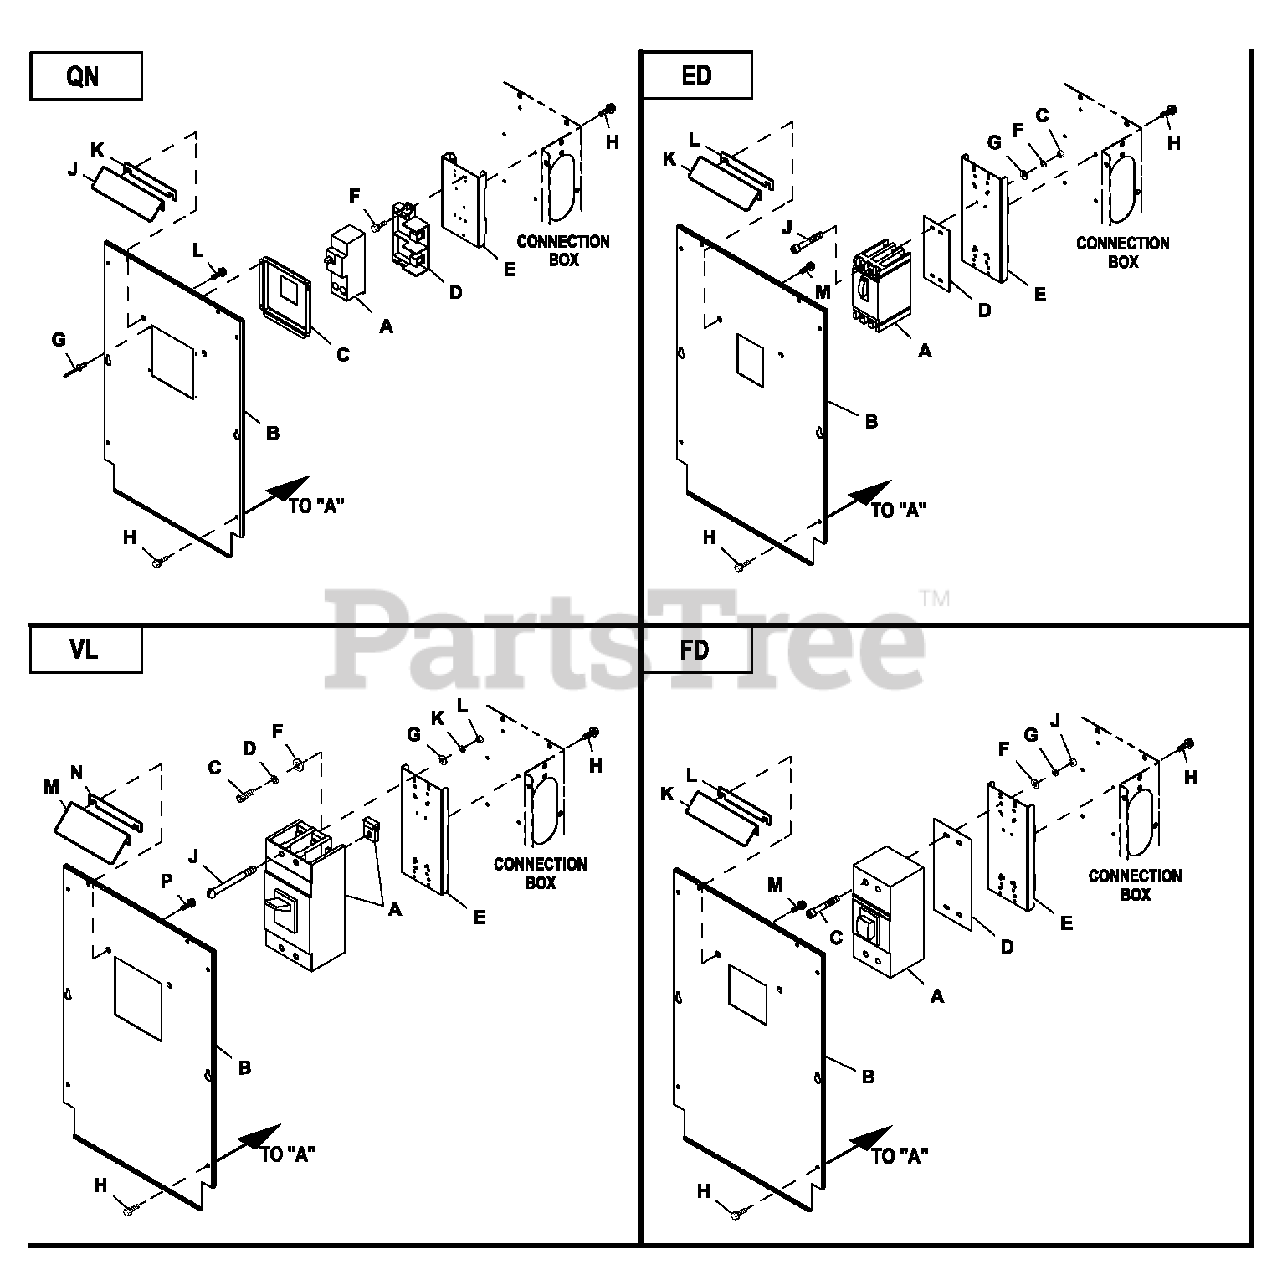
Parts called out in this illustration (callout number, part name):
A	CB 0175A2P 240V S Q N 2 LL
B	COVER CB C2 CPL
C	COVER CB DISH 2P S Q N
D	BASE, Q N CIRCUIT BREAKER
E	STA N DOFF CB BOX CO N BOX
F	SCREW HHTT M5-0.8 X 10 BP
G	RIVET POP .125 X .275 SS
H	SCREW HWHT M6-1 X 16 N WA Z/JS
J	SHIELD-SM CIRCUIT BREAKER
K	GASKET-CB SHIELD C2
L	SCREW HWHTF M6-1.0X16
A	CB 0125A3P 480V S ED4 LL
B	COVER CB S ED C2 CO NBOX
C	N UT HEX #10-32 STEEL
D	I N SULATOR CB S(ED-3P)
E	STA N DOFF CB MOU NT CO N BOX
F	WASHER LOCK #10
G	WASHER FLAT#10ZIN C
J	SCREW RHM #10-32 X 4-1 /2
K	SHIELD-SM CIRCUIT BREAKER
L	GASKET-CB SHIELD C2
M	SCREW HWHTF M6-1.0X16
A	CB 0300A 3P 600V S JG-VL LL
B	COVER CB S JG VL C2 CONBOX
C	SCREW SHC M8-1.25 X 20 C12.9
D	WASHER LOCK M8-5/16
E	STANDOFF CB MOUNT CONBOX
F	WASHER FLAT 5/16-M8 ZINC
G	WASHER FLAT#10ZINC
J	SCREW RHM 10-32X4
K	WASHER LOCK #10
L	NUT HEX #10-32 STEEL
M	SHIELD-LGE CIRCUIT BREAKER
N	GASKET-CB SHIELD C2
P	SCREW HWHTF M6-1.0X16
A	CB 0150A3P 600V S FD6 LL
B	COVER CB S FD6 C2 CONBOX
C	SCREW SHC 1/4-20X4.5 G8.8 NZ
D	INSULATOR CB FD FRAME 30MIL
F	WASHER FLAT 1/4-M6 ZINC
G	WASHER LOCK M6-1/4
J	NUT HEX 1/4-20 STEEL
